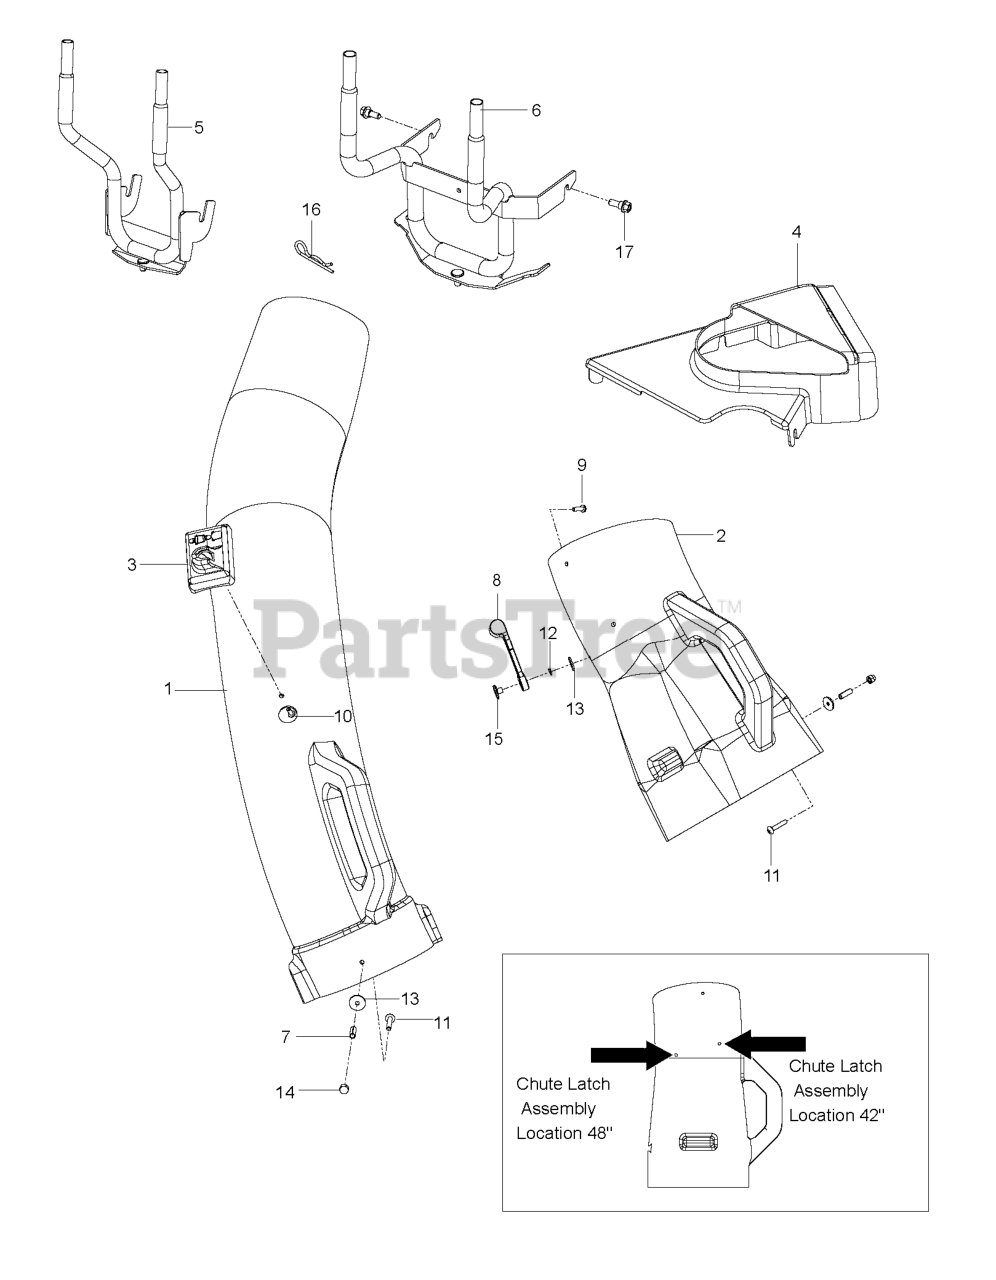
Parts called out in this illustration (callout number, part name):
1	CHUTE, UPPER - TRIMMED
1	UPPER CHUTE 54"
2	CHUTE, MIDDLE - TRIMMED
3	DUMP BAG INDICATOR
4	SHIELD, BELT, 48
5	BELT, 48/52"
6	BAGGER.ASM.SUPPORT.GT.TEX.BLAC
7	BRACKET.BAGGER.3-BIN.BLACK
8	COVER, BELT
9	DECAL, BELT ROUTING
10	DECAL, NO STEP
11	KNOB W/STUD
12	HOOD LATCH
13	BSHG .202X.75 LG SPLIT ZD SPEC
14	SHOULDER BOLT, SELF-TAP
15	SCREW #10-24 X 5/8
16	SCREW
17	SCREW #10-24 X 1-1/8 ZD SPEC
18	NUT 10-24 ACORN ZD
19	NUT 10-24 WELD PLATED
20	WASHER - 3/16 LOCK ZD
